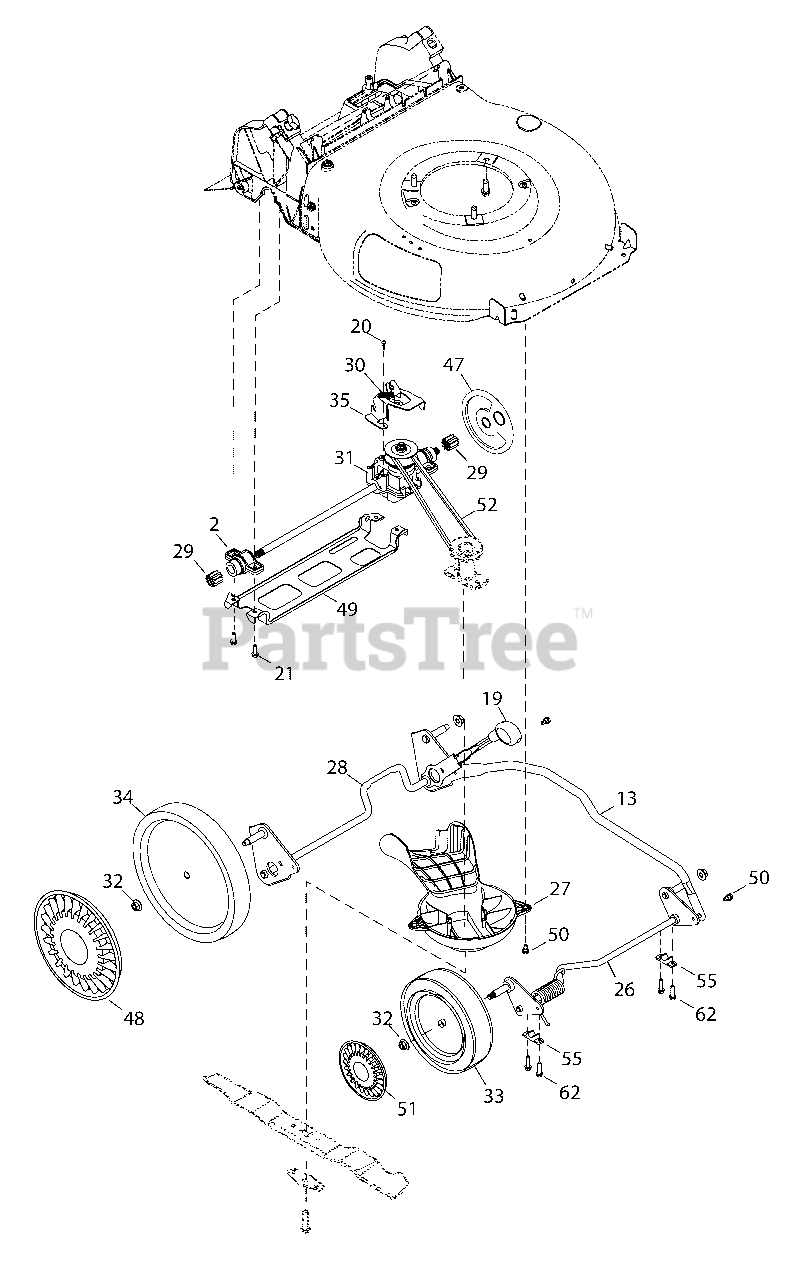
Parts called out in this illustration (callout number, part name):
2	ASSEMBLY, Bearing
13	CROSS BRACKET
19	KNOB, Adjustment Lever
20	SCREW, Hex Washer Head, .159 x .43
21	CAPSCREW, Hex Head Flange Taptite, 1/4-15 X 1-1/4
26	AXLE ASSEMBLY, Front
27	BAFFLE, Engine
28	AXLE ASSEMBLY, Rear
29	GEAR, 9T
30	SPRING, Extension, 2.405
31	TRANSMISSION
32	NUT, Hex Flange, Nylock, 3/8-16
33	WHEEL, Front
34	WHEEL, Rear
35	BRACKET, Transmission
47	COVER, Wheel, Dust
48	HUBCAP, Rear, 11" Grey
49	BRACKET, Rear Support
50	SCREW, Shoulder, 1/4-20 x 1/2
51	HUBCAP, Front, 8" Grey
52	V-BELT, 3L, 31.25"
55	BUSHING, Bearing, Front Crossbar
62	SCREW, Self Tapping, 1/4-15 x 1-1/4
